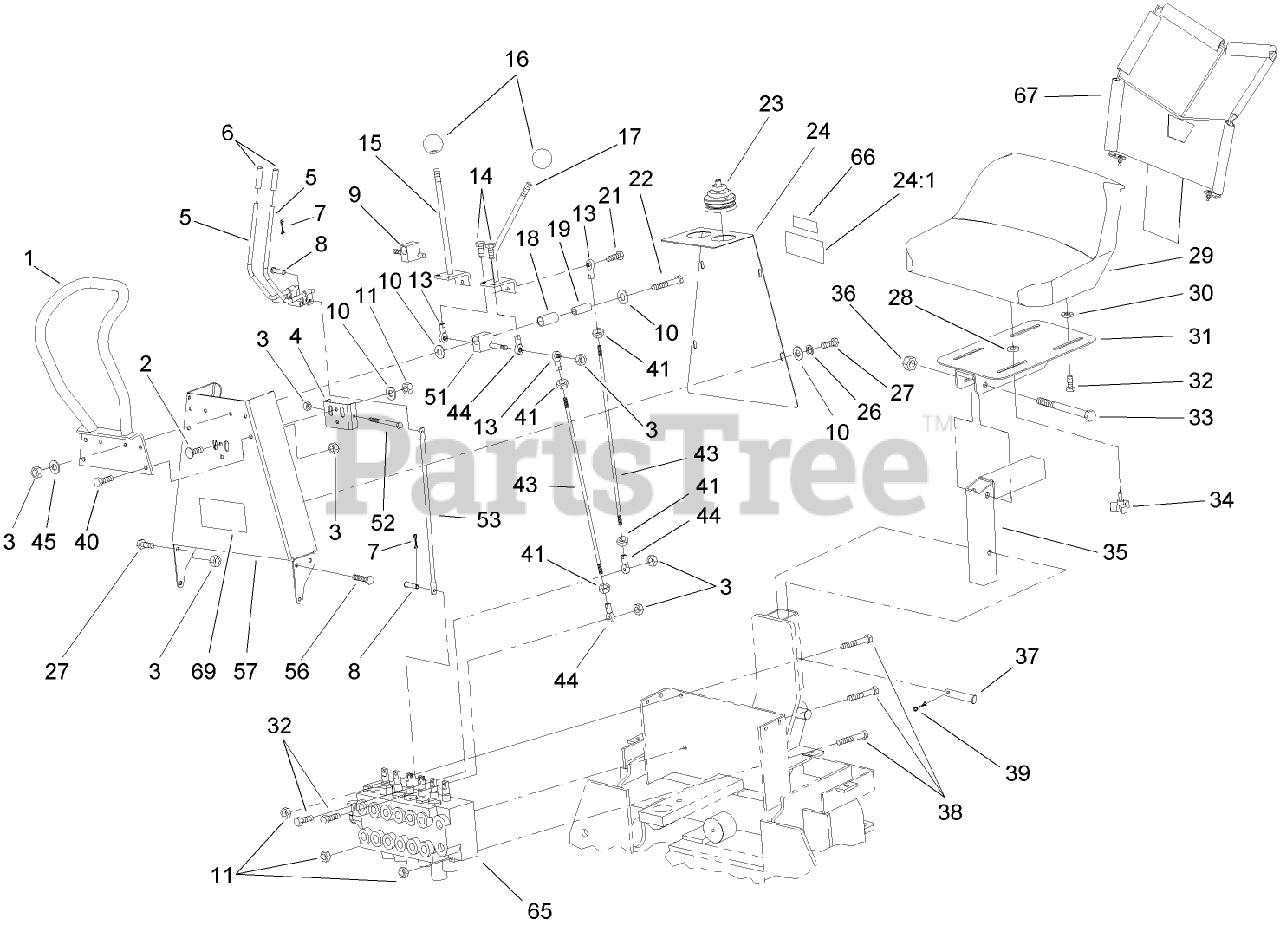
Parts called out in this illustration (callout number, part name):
1	REFERENCE BAR ASM
2	BOLT-CARR
3	NUT-LOCK
4	U-BRACKET
5	STABILIZER ROD ASM
6	CAP-RUBBER
7	PIN-COTTER
8	PIN-CLEVIS
9	RH PIVOT ASM
10	WASHER-PLAIN
11	NUT-LOCK, NI
13	JOINT-ARTICULATED
14	SCREW-HH
15	RH CONTROL HANDLE ASM
16	KNOB-BALL
17	LH CONTROL HANDLE ASM
18	BUSHING-BRONZE
19	BUSHING
21	SCREW-HH
22	SCREW-HH
23	BOOT-LEVER, CONTROL
24	VALVE-REAR PLATE, COVER
24:1	DECAL-WARNING
26	WASHER-LOCK
27	SCREW-HH
28	SPACER-NYLON
29	SEAT
30	SPACER-NYLON
31	SEAT PLATE ASM
32	BOLT-SHOULDER
33	SCREW-HH
35	SEAT POST ASM
36	NUT-HEX
37	PIN-CLEVIS
38	SCREW-HH
39	PIN-COTTER
40	SCREW-HH
41	NUT-HEX
43	ROD-CONTROL
44	BALLJOINT-RH
45	WASHER-PLAIN
51	LH PIVOT ASM
52	SCREW-HH
53	ROD-STABILIZER
56	SCREW-HH
57	FRONT SHROUD ASM
65	HYDRAULIC VALVE ASM
66	DECAL-CONTROL
67	BACKHOE SHIELD KIT
69	DECAL
